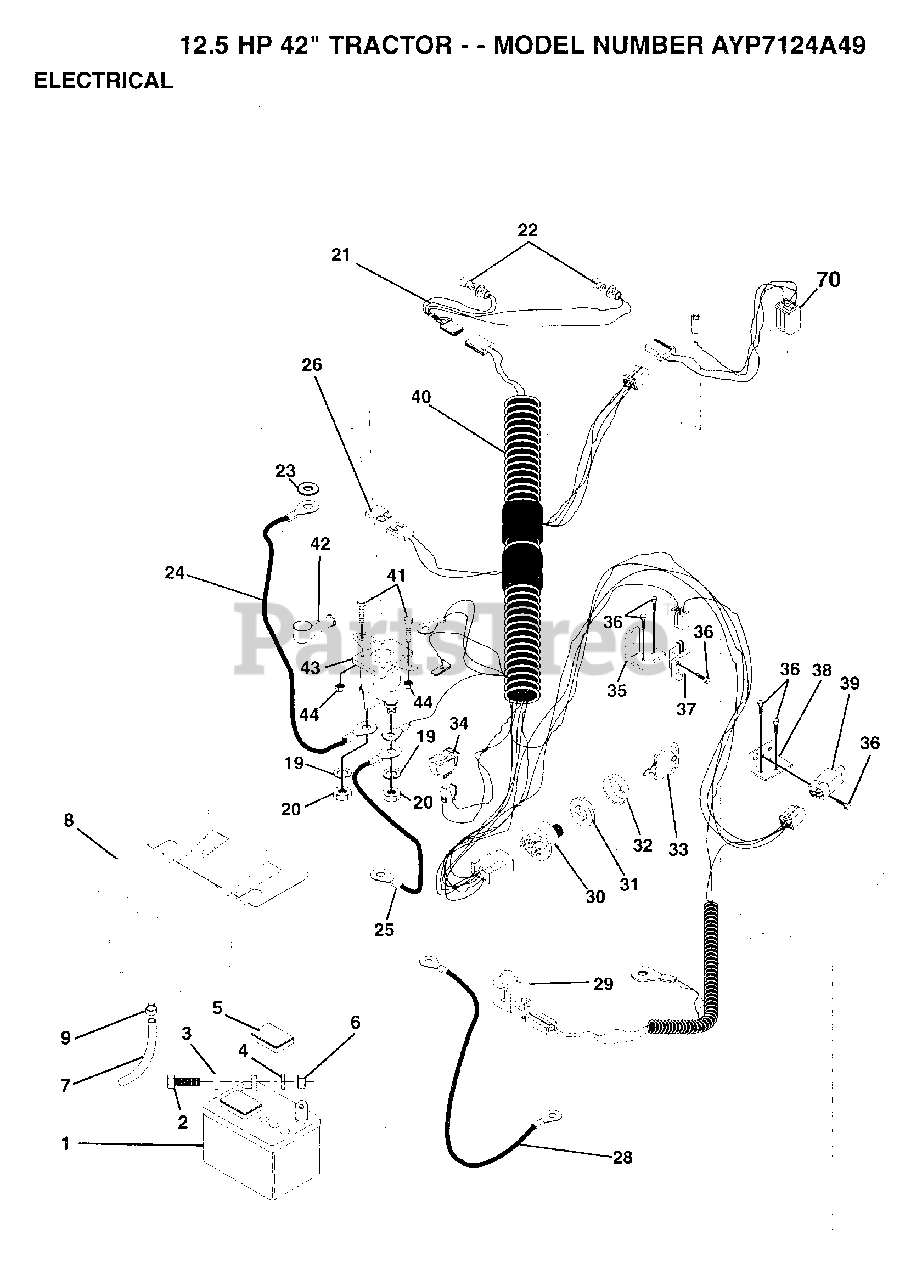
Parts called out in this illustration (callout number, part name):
2	BOLT LT
3	WASHER
4	LOCKWASHER
5	"CAP,BATTERY "
7	TUBE T
9	HOSE CLAMP T
20	NUT
21	"HARNESS,LIGHT SOC"
22	HEADLAMP BULB
23	LOCKWASHER
24	"CABLE T, BATTERY"
26	FUSE HYT
28	CABLE T
29	SWITCH SEAT
33	KEY STEEL DELTA
34	SWITCH LT
35	BRACKET LT
36	SCREW
37	SWITCH-INTER. GT
38	SWITCH BRACKET
39	SWITCH INTERLOCKT
40	HARNESS IGN DASH
41	BOLT HXHD FIN
44	NUT HXKEP 1/4X20
70	HARNESS ENG DUAL
